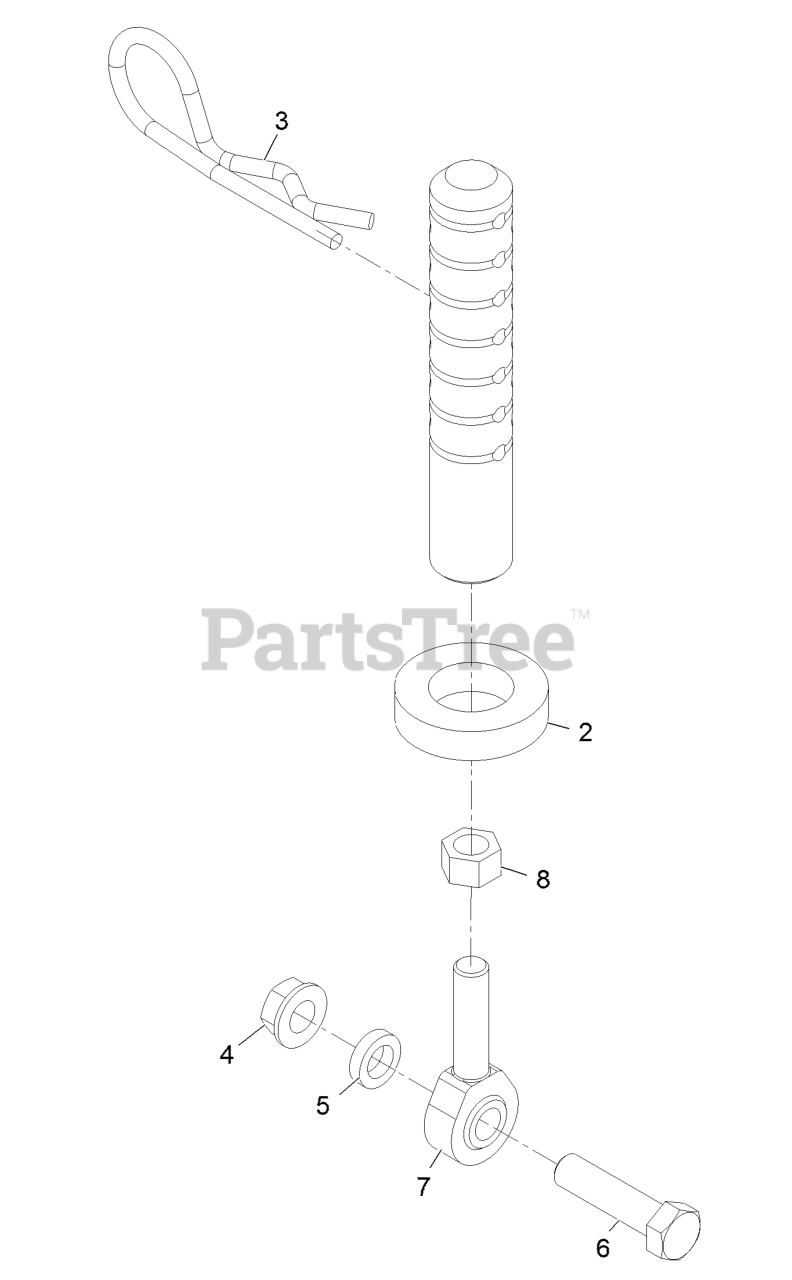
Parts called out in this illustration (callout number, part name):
2	SPACER-DECK SUPPORT
3	PIN-CUT HEIGHT
4	NUT-HHF, WHIZ
5	SPACER-IDLER
6	SCREW-HH
7	BALLJOINT
8	NUT-HJ
